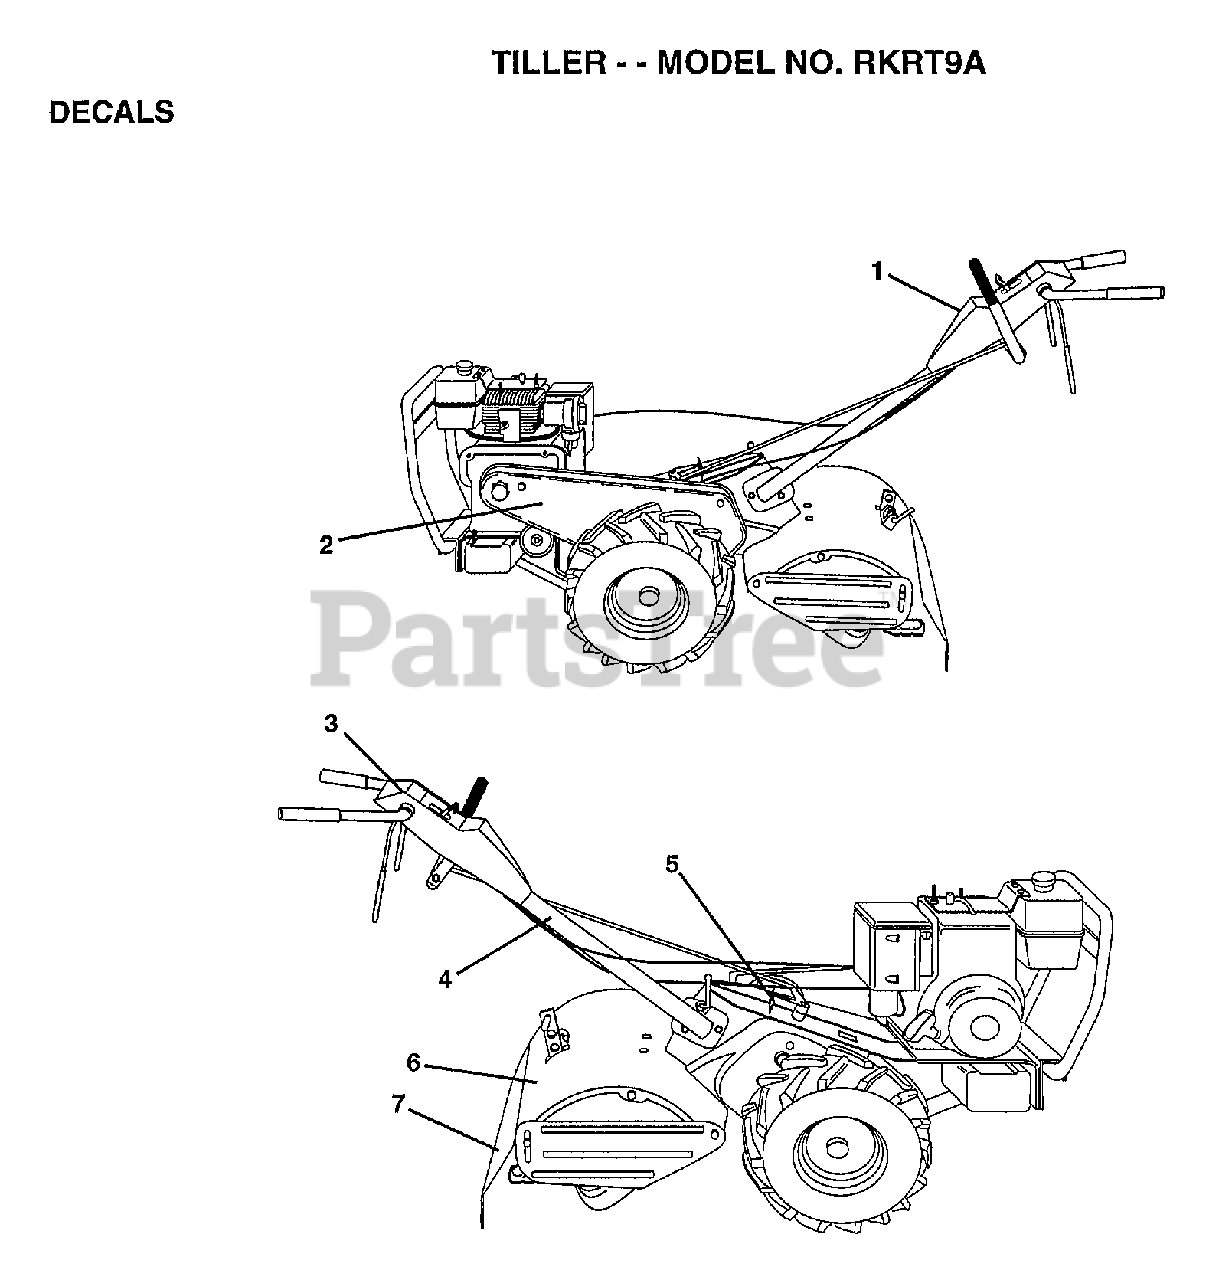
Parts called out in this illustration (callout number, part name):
1	DECAL, LOGO
2	DECAL.BELT.GRD.9HP
3	DECAL INST PNL 21
4	DECAL TI
5	DECAL.SHIFT.IND.
6	DECAL.CAUTION
